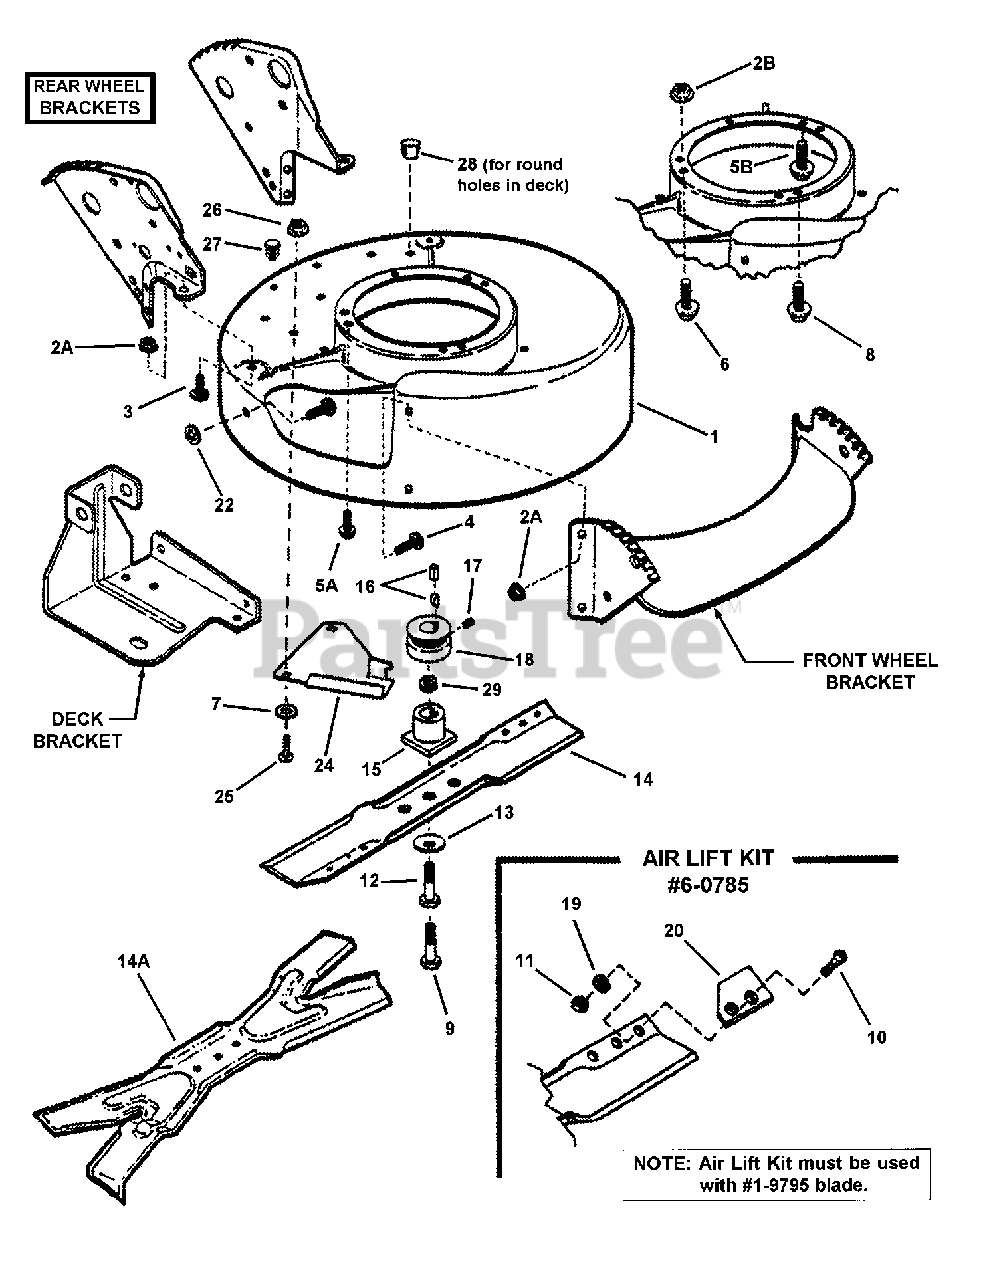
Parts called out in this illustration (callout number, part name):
1	DECK, Mower (Includes painted deck with decals)
2	NUT, 5/16-18 Hex Flange Lock, GR5
3	BOLT, 5/16-18 x 1/2" Short Neck Carriage GR5
4	BOLT, 5/16-18 x 1-1/8" Short Neck Carriage GR5
5A	SCREW, 3/8-16 x 1" Self-Tap (engine mount)
5B	SCREW, 3/8-16 x 1" Self-Tap (engine mount)
6	BOLT, 5/16-18 x 1-1/2" Hex Flange Lock, GR5
7	WASHER, 1/2" Flat
8	BOLT, 5/16-18 x 5/8" Hex Flange Lock GR5
9	SCREW, 3/8-24 x 1-3/4 Hex Head Cap GR5
10	SCREW, 5/16-24 x 21/32" Oval Head Machine
11	NUT, 5/16-24 Hex, GR5
12	SCREW, 3/8-24 x 2" Hex Head Cap, GR5
13	WASHER, Cone
14	BLADE, Cutter (Standard Lift) (20.75")
14A	BLADE, 21" Ninja (Quad Edge) (20.75")
14B	BLADE, Cutter (European) (20.75")
15	HUB, Blade Drive 25mm
16	KEY, Woodruff #505 Hi-Pro
17	SCREW, 5/16-18 x 5/16" Hex Socket Set
18	PULLEY, Engine, (25mm x 2.12")
19	WASHER, 5/16" Internal Tooth Lock
20	LIFT, Air
21	BOLT, 5/16-18 x 3/4" Short Neck Carriage GR5
22	RETAINER, 5/16" Bolt
24	BAFFLE, Belt
25	BOLT, 5/16-18 x 1/2" Short Neck Carriage GR5
26	NUT, 5/16-18 Hex Flange Lock, GR5
27	PLUG, Hole
28	PLUG, 5/16" Round Hole
29	SPACER, Blade Hub (1/16" thick)
